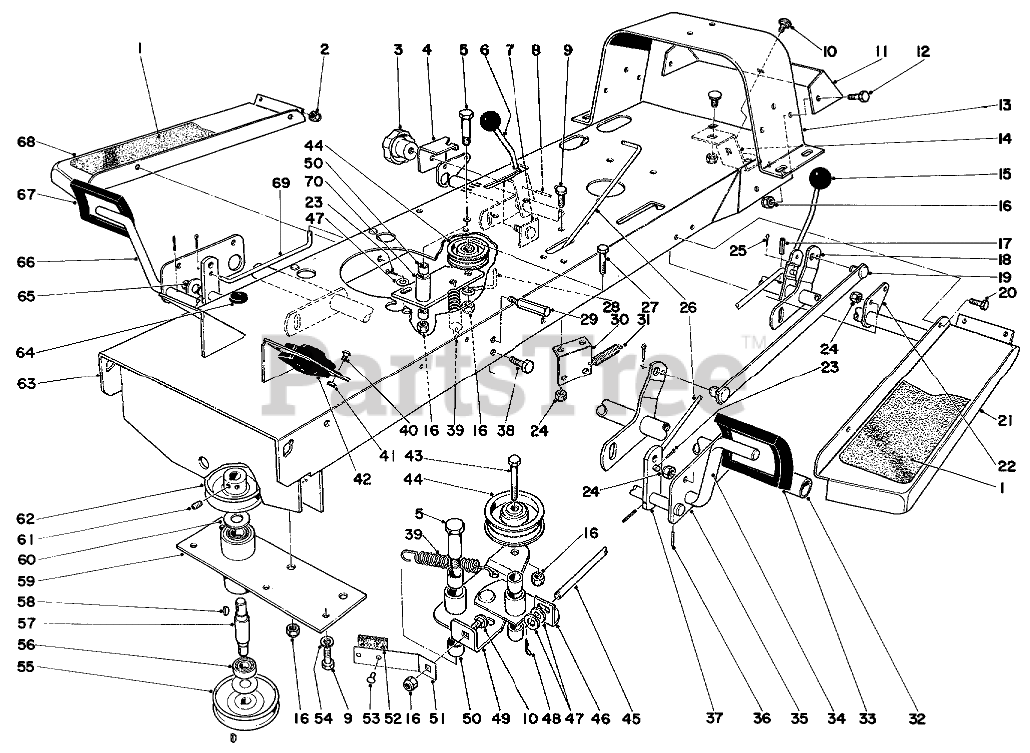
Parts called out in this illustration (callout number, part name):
1	Foot Pad
2	NUT-KEPS
4	Slide Height Adj.
5	Shoulder Bolt
6	Rod Control Hgt. Adj.
7	Knob Plate
8	PIN-ROLL
9	SCREW-HH
10	SCREW-CARR
11	Frame Member Rear
12	SCREW-HH
13	Rear Support
14	Bracket Hitch
15	KNOB-CONTROL
16	NUT-LOCK, CONE
17	1/8 X 1-3/8 ROLL PIN
18	Rear Height Adj. Tube
19	Height Adj. Link
20	SCREW-HH
21	Footrest
22	Bracket Tube
23	PIN-COTTER
24	NUT-LOCK, CONE
25	PIN-COTTER
26	Brake Rod
27	SCREW-HH
28	Belt Retainer
29	Pedal Stop
30	Belt Guide
31	Spring
32	Front Height Adj. Tube
33	CLUTCH PAD
34	Clutch Pedal
35	Plate Tube
36	PIN-SPRING
37	Arm Lever
38	SCREW-HH
39	Spring
40	SCREW-PTH
41	NUT-LOCK, SIDE
42	Mount Rubber
43	SCREW-HH
44	PULLEY-IDLER
45	Clutch Rod Blade
46	Pivot Bracket
47	WASHER-FLAT
48	PIN-COTTER
49	Idler Plate
50	BUSHING
51	Clutch Brake
52	BLADE BRAKE LINING
53	Rivet
54	WASHER-LOCK
55	Pulley
56	Bearing
57	Pulley Shaft
58	KEY-WOODRUFF
59	Pulley Tube
60	Bearing Washer
61	SCREW-SET, HSH
62	Pulley
63	Frame
64	GROMMET
65	WASHER-FLAT
66	Brake Pedal
67	PAD-BRAKE
68	Footrest
69	Clutch Rod
70	Idler Arm
